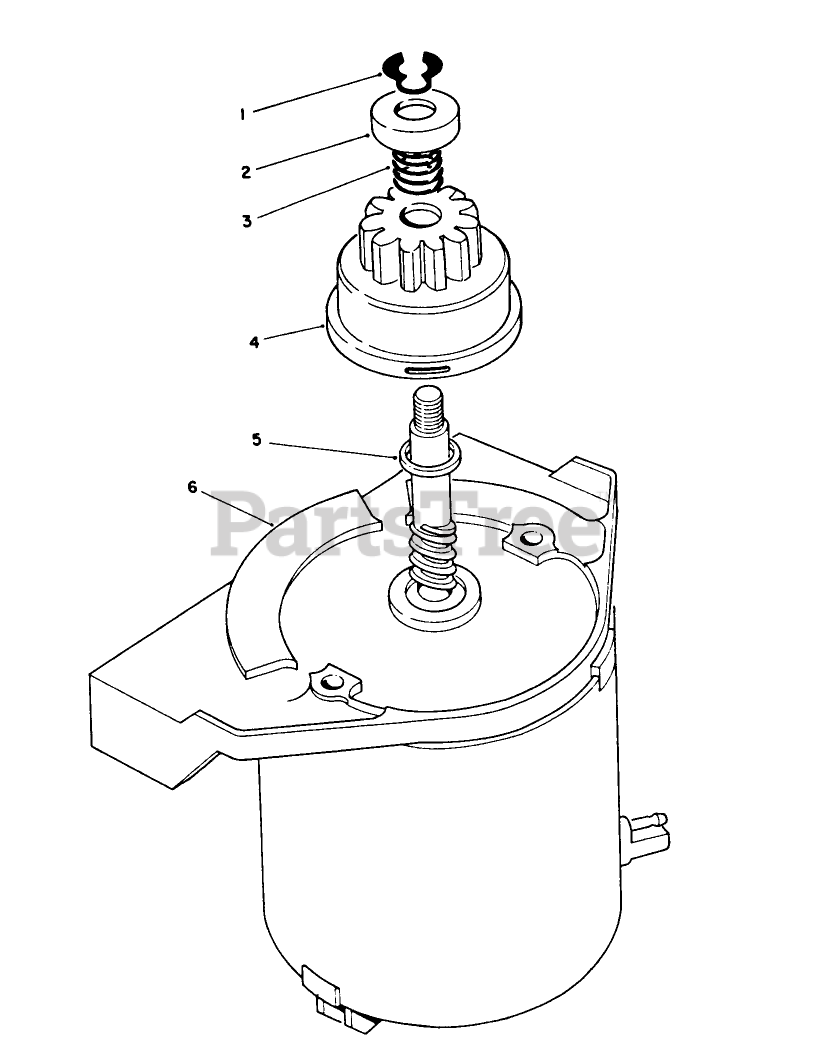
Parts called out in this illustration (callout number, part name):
1	RING-RETAINING
2	PINION STOP
3	COMPRESSION SPRING
4	PINION ASM
5	SPACER
6	END FRAME ASSY, MOTOR
